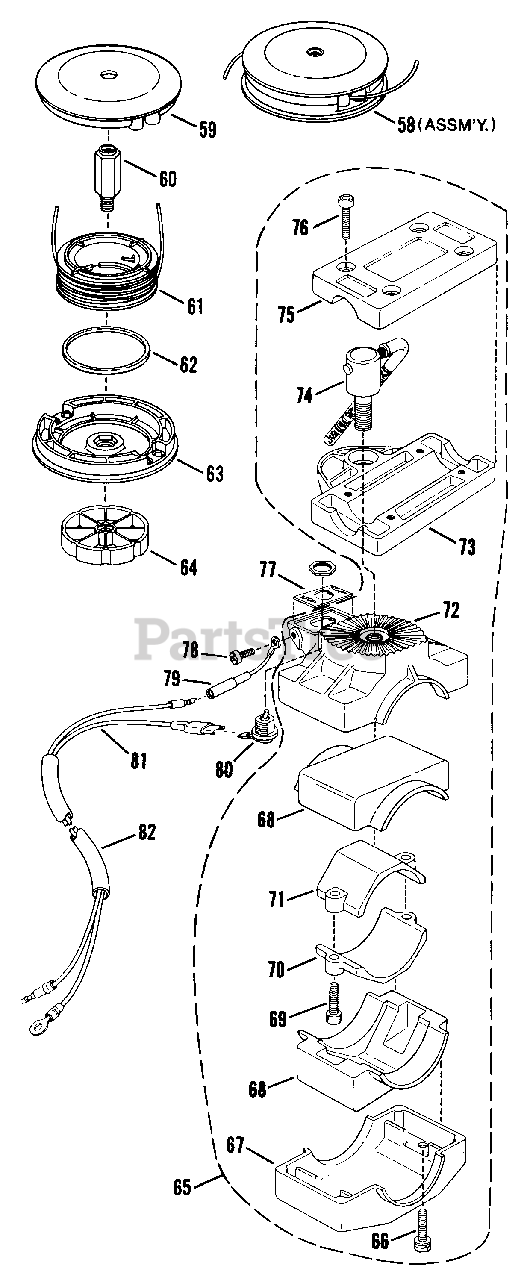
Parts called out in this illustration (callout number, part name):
58	MANUAL HEAD ASSM'Y
59	HOUSING, Upper
60	ARBOR (10mm hole)
61	SPOOL & LINE
63	HOUSING, Lower
64	KNOB, Lock
65	SWIVEL HANDLE ASSM'Y
66	BOLT, M6 x 30mm, Hex
67	JOINT "C", Handle
68	RUBBER, Vibro
69	SCREW, M6 x 25mm, Allen H
70	FITTING "B", Tube
71	FITTING "A", Tube
72	JOINT "D", Handle
73	JOINT "B", Handle
74	LOCK HANDLE
75	JOINT "A", Handle
76	SCREW, M5 x 20mm, Allen Hd.
77	PLATE, Switch
78	SCREW, M5x10mm
79	LEAD, Wire (Ground)
80	SWITCH, Stop
81	WIRE LEADS
